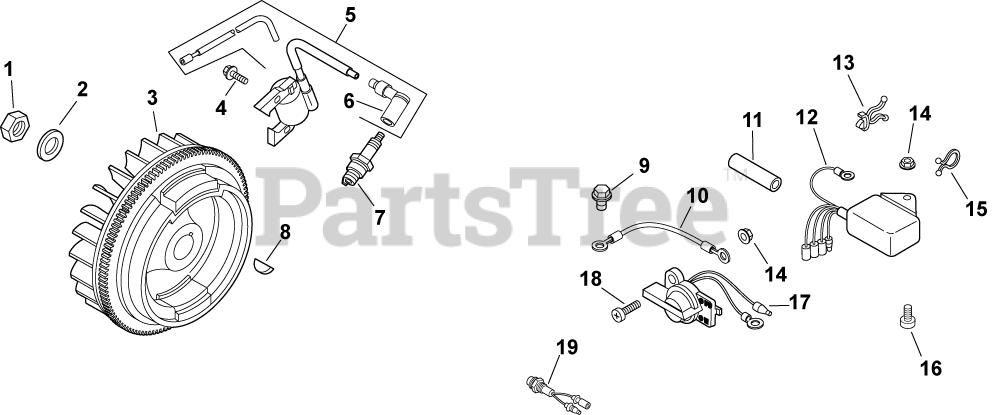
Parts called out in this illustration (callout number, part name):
3	FLYWHEEL FOR 600 SERIES
5	KIT, IGNIT MODULE (600 SERIES)
6	CAP ASSEMBLY
7	SPARK PLUG
8	KEY, WOODRUFF
11	SLEEVE, WIRING
12	OIL SWITCH ASSEMBLY -USE 63 099 03-S
13	CLAMP, WIRE
14	NUT, STOP SWITCH
16	SCREW, PAN HEAD
17	STOP SWITCH
18	SCREW, STOP SWITCH
19	OIL LIGHT
